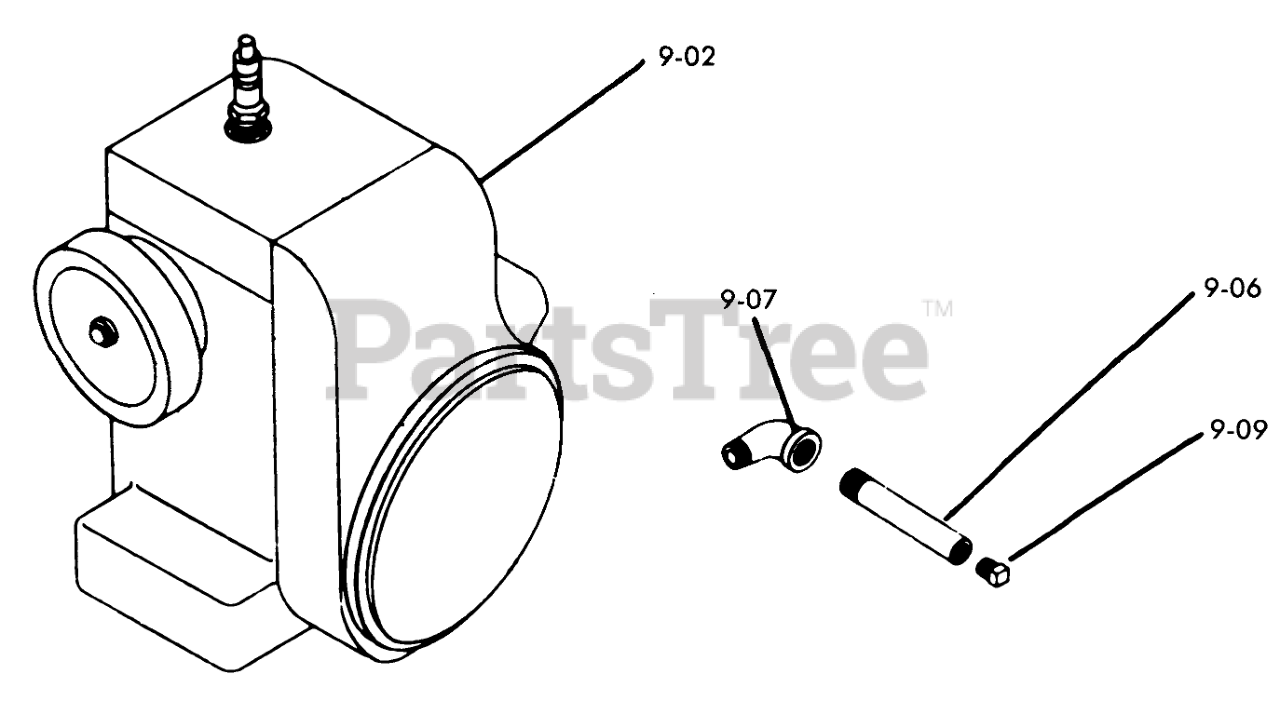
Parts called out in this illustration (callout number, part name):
9-02	Engine-16HP Kohler
9-06	Nipple 3/8 x 5
9-07	ELBOW-STREET
9-09	Cap
